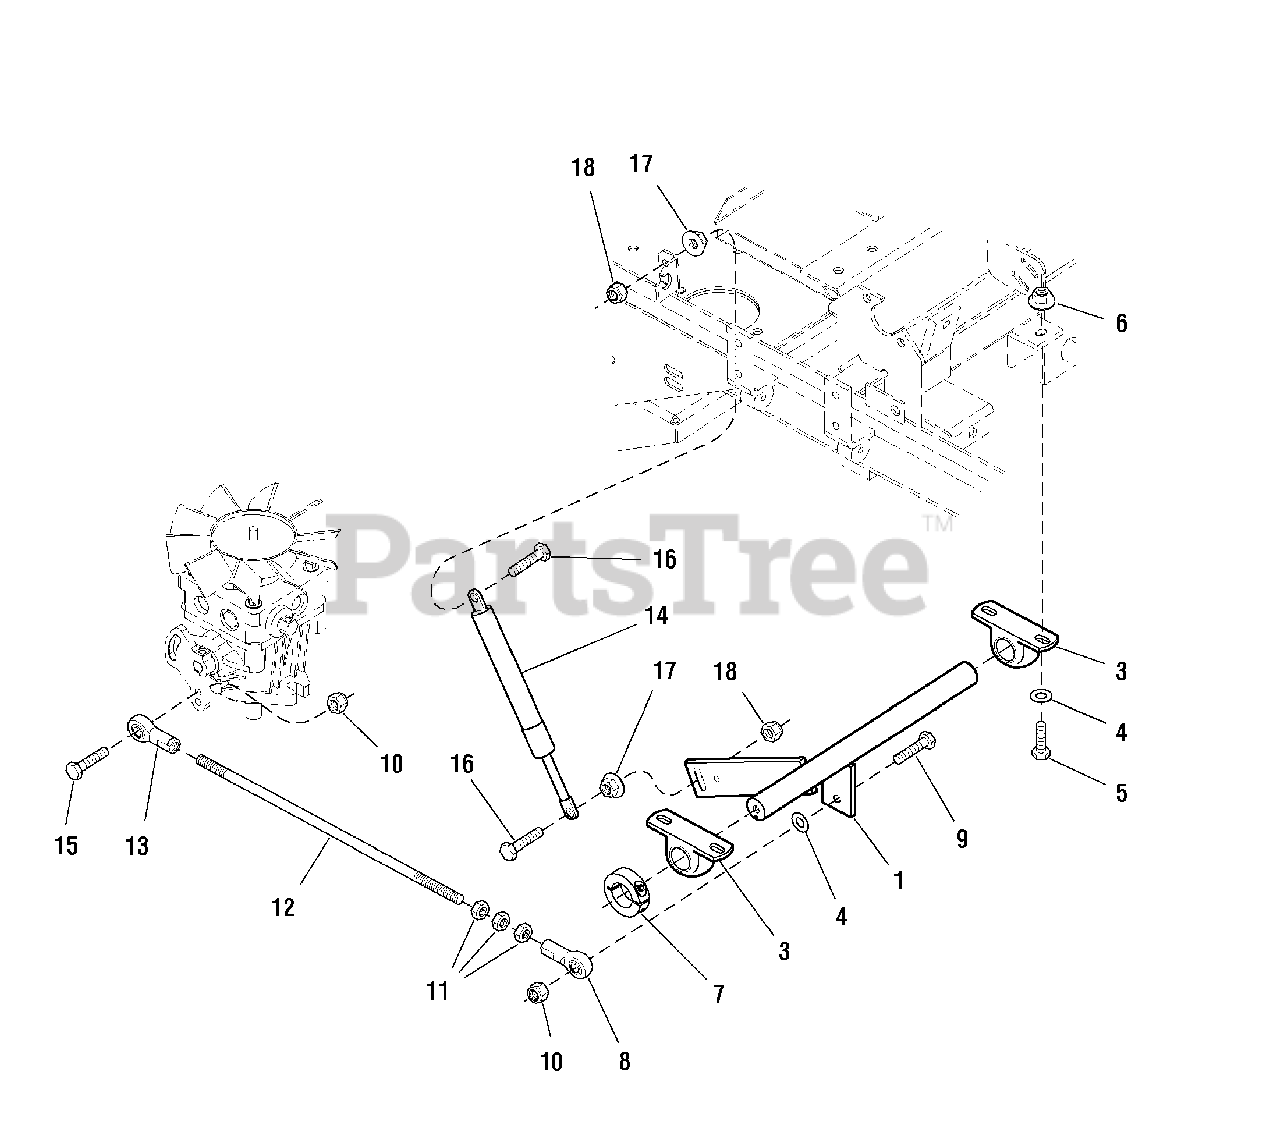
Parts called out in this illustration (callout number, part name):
1	CONTROL SHAFT-RH
2	CONTROL SHAFT-LH
3	BEARING, Pillow Block
4	WASHER, 5/16
5	CAPSCREW, Hex Hd, 5/16-18 x 1
6	NUT, Hex, Serrated Flange, 5/16-18
7	COLLAR, 1" Split
8	BALL JOINT 5/16-24 RH FEMALE STAMPED STL
9	CAPSCREW, Hex Hd, 5/16-18 x 1-1/4
10	NUT, Hex, Nylon Lock, 5/16-18
11	NUT, Hex, 5/16-24
12	HYDRO LINKAGE ROD
13	BALL JOINT 5/16-24 LH FEMALE STAMPED STL
14	DAMPENER
15	CAPSCREW, Hex Hd, 5/16-18 x 1-1/8
16	CAPSCREW, Hex Hd, M8-1.25 x 35MM
17	NUT, Hex, Serrated Flange, M8-1.25
18	NUT, Hex, Nylon Lock, M8-1.25
